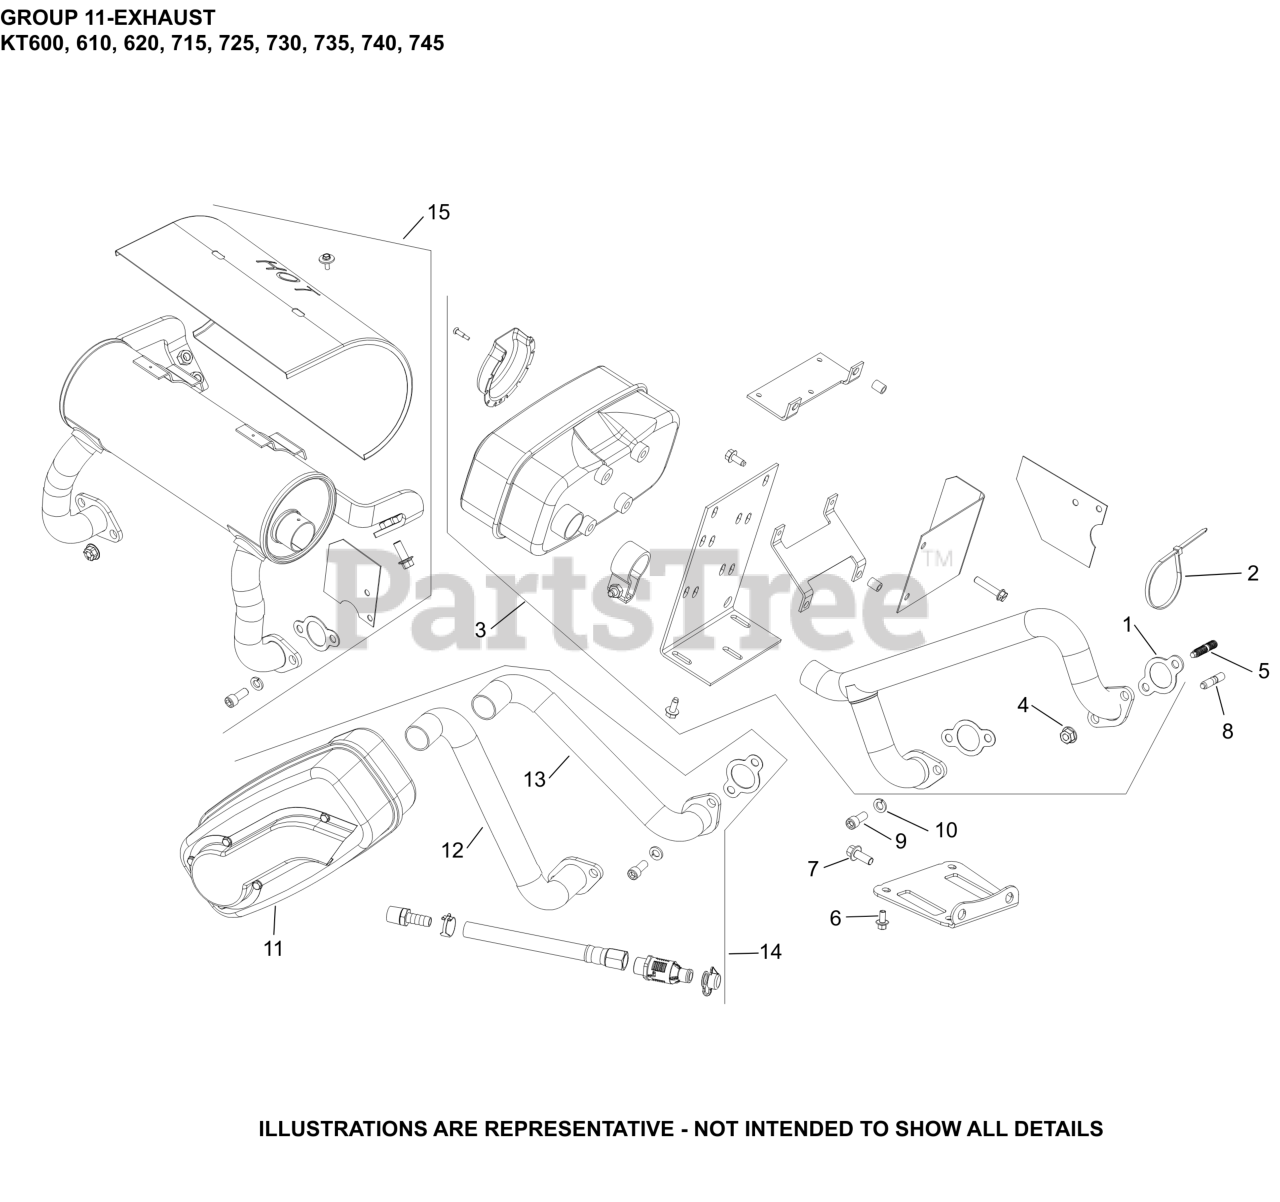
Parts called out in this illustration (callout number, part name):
1	GASKET, EXHAUST
4	NUT, HEX FLANGE LOCK (M8)
8	STUD, METRIC EXHAUST
